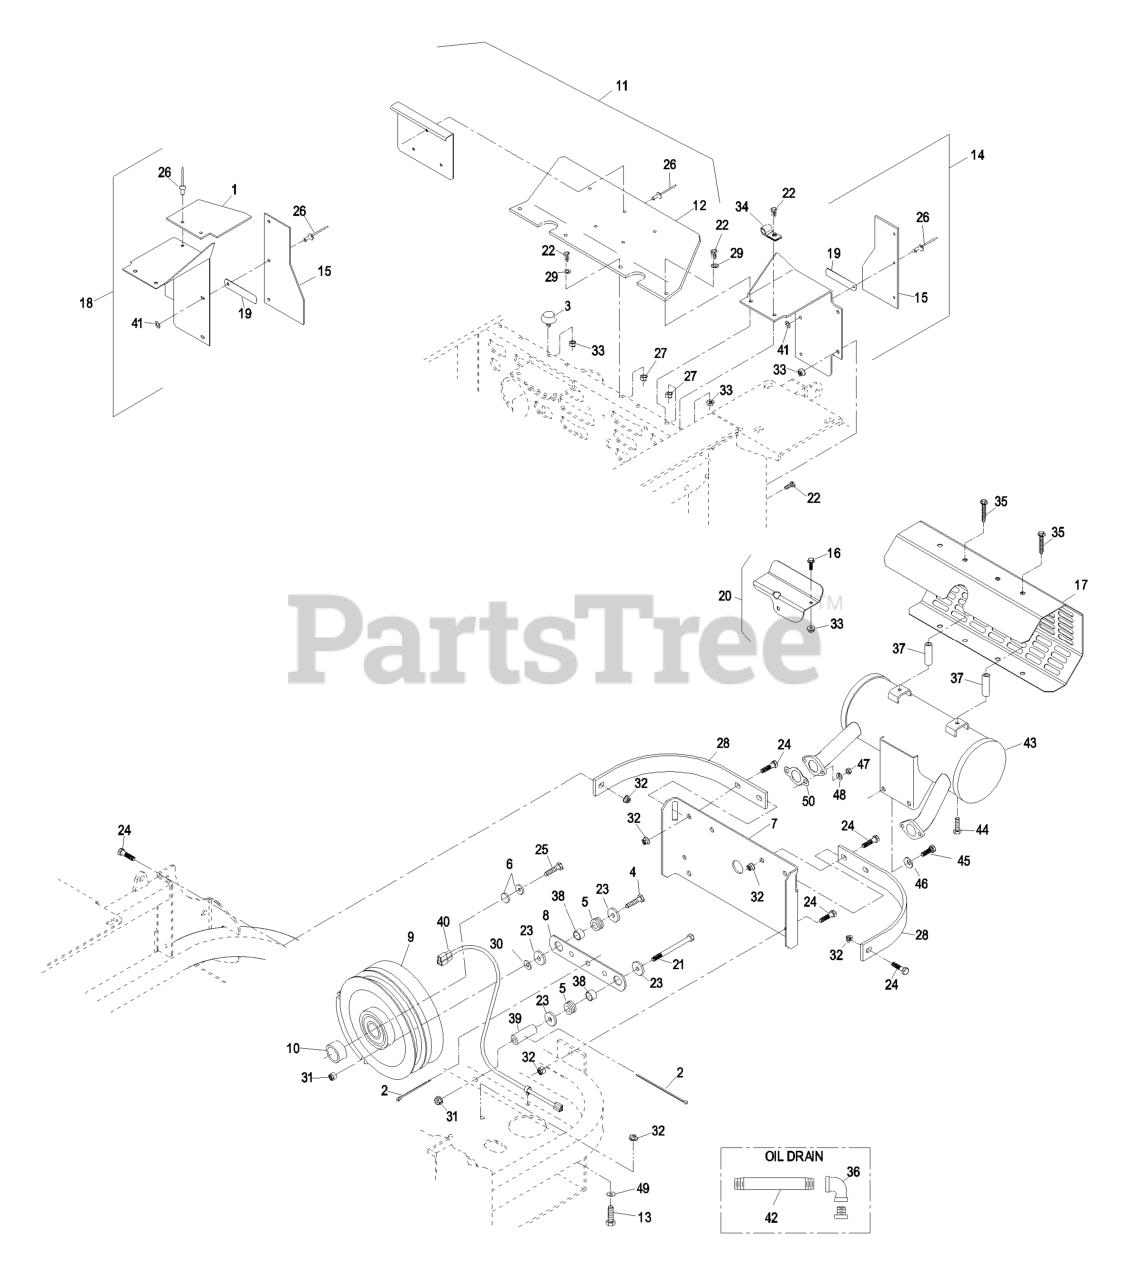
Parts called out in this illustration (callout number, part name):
1	BAFFLE-COOLER, ENGINE
2	TIE-PLASTIC
4	SCREW-HH
5	GROMMET
6	WASHER-SPRING
7	GUARD-CLUTCH
8	STRAP-CLUTCH, BRAKE
9	KIT-CLUTCH
10	SPACER-CLUTCH
12	SHIELD-ENGINE
13	SCREW-HH
15	SHIELD-ENGINE
16	SCREW-HH
17	GUARD-MUFFLER
18	RH SHIELD ASM
19	CLIP-BAFFLE, REAR
20	CABLE HEAT SHIELD KIT
21	SCREW-HH
22	SCREW-HH
24	SCREW-HH
25	SCREW-HH
26	RIVET-POP
27	NUT-LOCK, NI
28	STRAP-GUARD
29	WASHER-FLAT
30	WASHER-FLAT
32	NUT-HHF, WHIZ
34	CLIP-LOOM
35	SCREW-HWH
36	ELBOW-90 DEG
39	SPACER-ANCHOR, CLUTCH
40	KIT,CLUTCH JUMPER HARNESS
41	WASHER-FLAT
42	NIPPLE
43	KIT,MUFFLER KOHLER
44	SCREW
45	SCREW-HH
46	SCREW-HH
47	NUT-HEX
48	WASHER-LOCK
49	WASHER-BELLEVILLE
